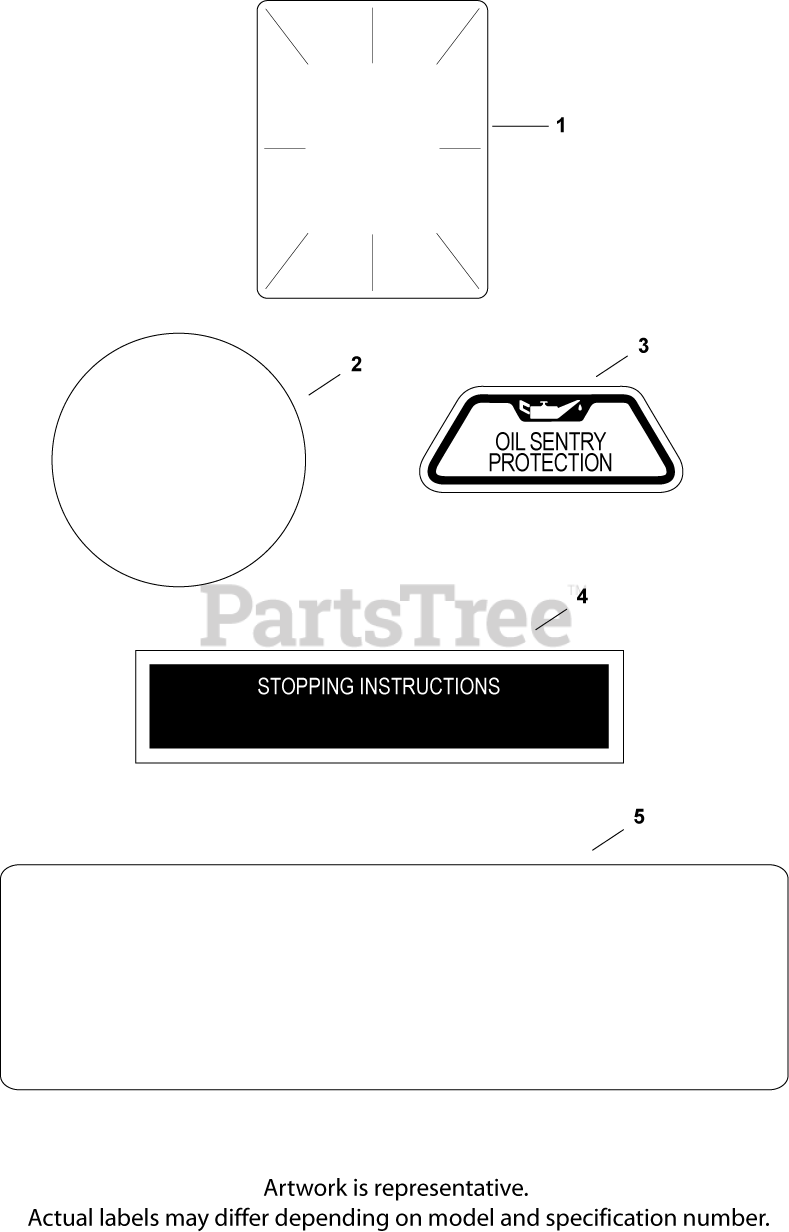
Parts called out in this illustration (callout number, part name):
1	DECAL, CLEAR LAMINATE USE 25 113 70-S
2	DECAL, GRASS SCREEN USE 24 113 499-S
3	DECAL, OIL SENTRY - (#DSC)
4	DECAL, STOPPING INSTRUCTION
5	DECAL, 18 HP
